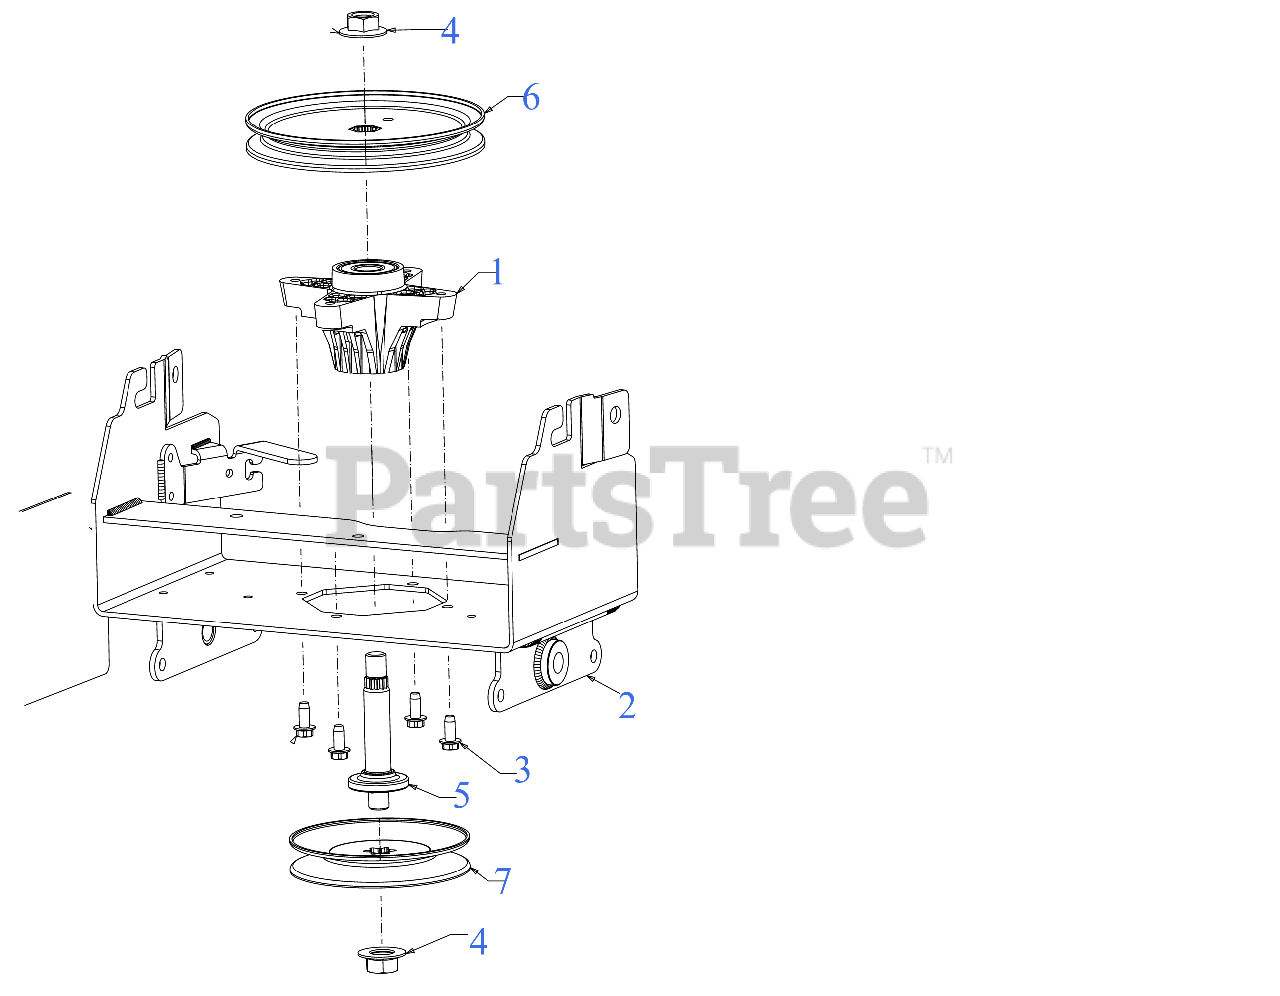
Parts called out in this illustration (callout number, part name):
1	SPINDLE HOUSING ASSEMBLY
2	SPINDLE MOUNTING BRACKET (POWDER BLACK)
3	SCREW 5/16-18 x .750
5	BLADE SPINDLE SHAFT 4.125 LG
6	V-PULLEY 7.25 DIA
7	V-PULLEY 5.57 DIA
